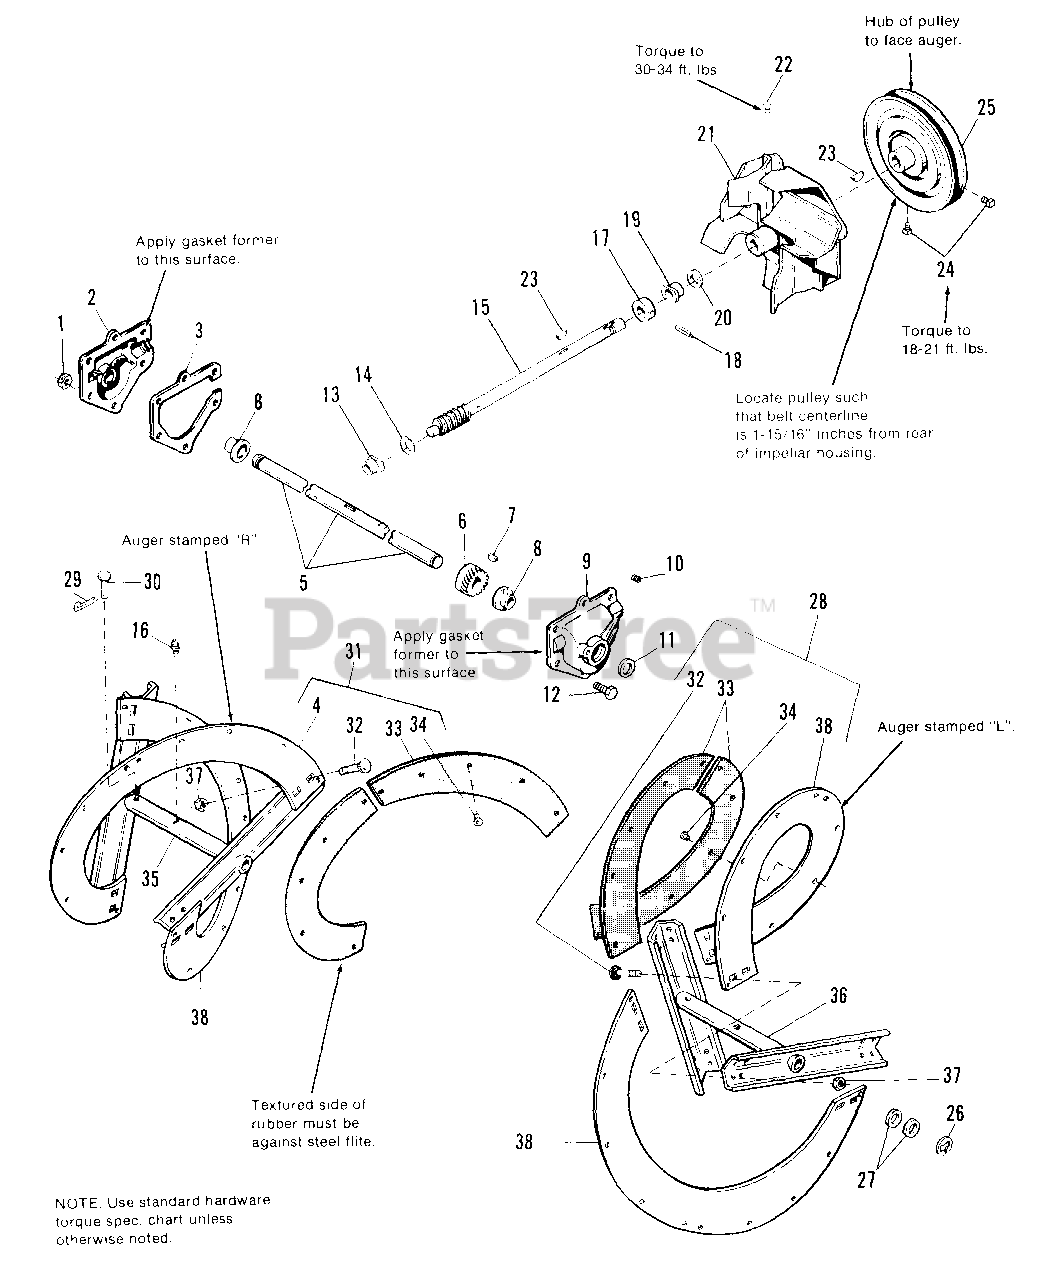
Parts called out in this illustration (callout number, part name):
1	NUT, Lock, 1/4-20 (Qty. 6 on 1691416 & 1691417)
2	GEAR CASE KIT, R.H. & L.H. (Incl. Ref. No. 2, 8 & 9) (1691172, 1691364 only)
2	GEAR CASE ASSY., R.H. (Incl. Ref. No. 8) (1691416 & 1691417 only)
3	GASKET, Gear Case (1691172, 1691364 only)
5	AUGER, Shaft
7	KEY, Woodruff
8	BUSHING, Auger Shaft
9	GEAR CASE KIT, R.H. & L.H. (Incl. Ref. No. 2, 8 &9) (1691172, 1691364 only)
10	PLUG, Pipe, 1/8-NPT, Gear Case
12	CAPSCREW, Hex, 1/4-20 x 7/8 (Qty. 6 on 1691416 & 1691417)
13	BUSHING, Worm Shaft
14	WASHER, Plain
16	GREASE FITTING, Auger Support Assy.
17	COLLAR, Thrust, Worm Shaft
18	PIN, Driv-lok, 3/16 x 1-1/2, Thrust Collar
19	BUSHING, Worm Shaft
20	SEAL, Oil, Impeller Assy. (1691172, 1691364 only)
21	IMPELLER ASSY.
22	SETSCREW, Sq. Hd., 3/8-16 x 1/2
23	KEY, Woodruff, 3/16 x 3/4
24	SETSCREW, Sq. Hd., 5/16-18 x 1/2
25	PULLEY, Input, Auger
26	RING, Retaining
27	WASHER
28	AUGER FLITE ASSY., L.H. (Incl. Ref. No. 32, Qty. 4; Ref. No. 33, Qty. 2; Ref. No. 34, Qty. 20; & Ref. No. 38, Qty. 1)
29	PIN, Cotter, 3/4
30	PIN, Shear, Auger Support Assy.
31	AUGER FLITE ASSY., R.H. (Incl. Ref. No. 32, Qty. 4; Ref. No. 33, Qty. 2; Ref. No. 34, Qty. 20; & Ref. No. 4, Qty. 1)
32	BOLT, Carriage, 1/4-20 x 5/8
33	FLITE, Rubber, Auger Blade
34	RIVET, 3/16" Tubular
35	AUGER SUPPORT ASSY., R.H. (Incl. Ref. No. 16, Qty. 1)
36	AUGER SUPPORT ASSY., L.H. (Incl. Ref. No. 16, Qty. 1)
37	NUT, Hex Lock, 1/4-20
